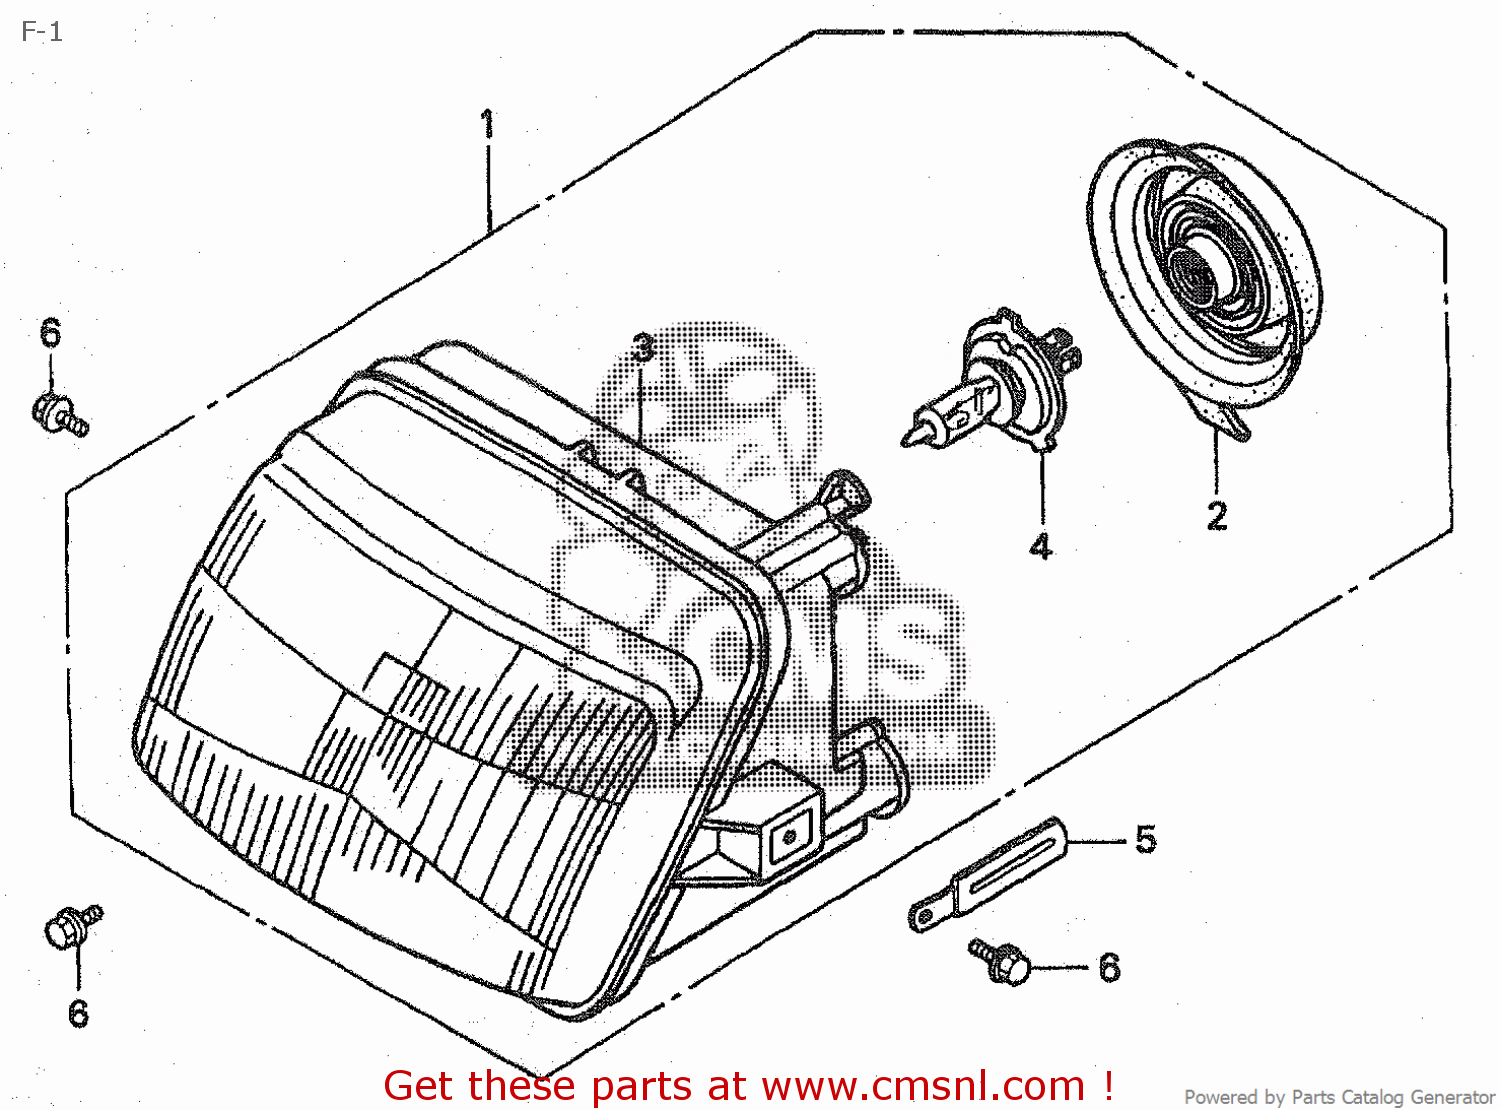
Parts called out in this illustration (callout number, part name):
2	COVER RUBBER
3	HEADLIGHT UNIT
4	BULB,HEADLIGHT
5	CLIP,WIRE HARNESS
6	BOLT,FLANGE,6X16
